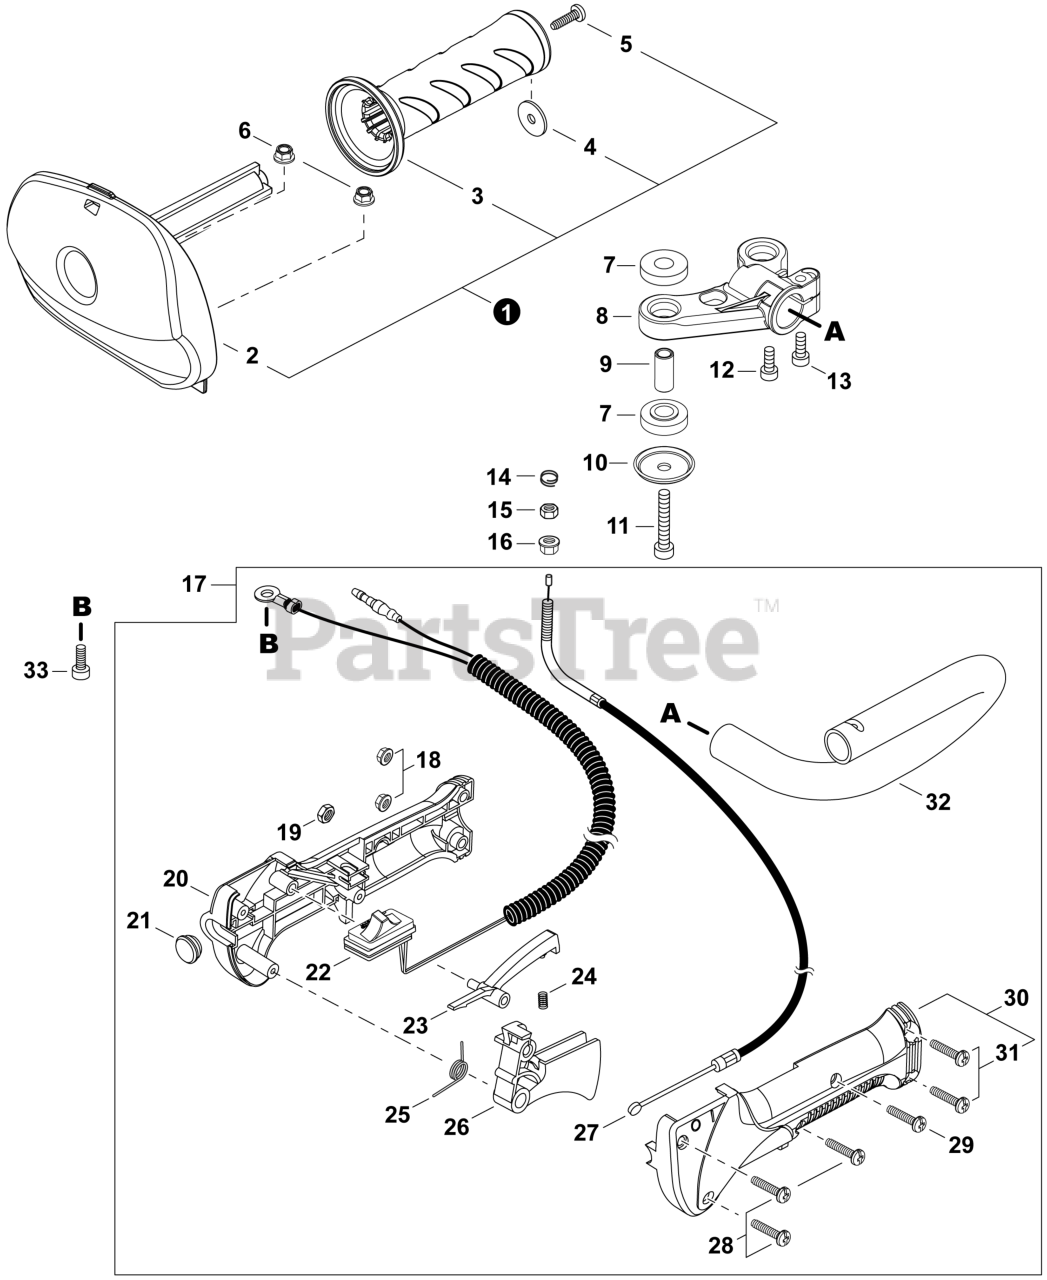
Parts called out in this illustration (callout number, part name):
1	HANDLE ASSY, FRONT
2	HANDLE, FRONT
4	WASHER 5 MM
5	BOLT, TORX 5x20
6	NUT, FLANGE M5
7	CUSHION
8	BRACKET, HANDLE
9	COLLAR 6
10	WASHER 6
11	BOLT, TORX 6
12	BOLT, TORX 5x20
13	BOLT, TORX 5x12
16	NUT, FLANGE M6
17	HANDLE ASSY, REAR
18	NUT, LOCK
20	CONTROL HANDLE - RIGHT
21	PLUG, RUBBER
22	SWITCH ASSY, ON-OFF
23	LOCKOUT, THROTTLE
24	SPRING, COMPRESSION
25	SPRING, TORSION
26	TRIGGER, THROTTLE
27	CABLE, THROTTLE
28	SCREW, TAPPING 4x16
29	SCREW M4x23
30	CONTROL HANDLE KIT
31	SCREW M5x22
32	HANDLE, REAR
33	BOLT, TORX 4x10
